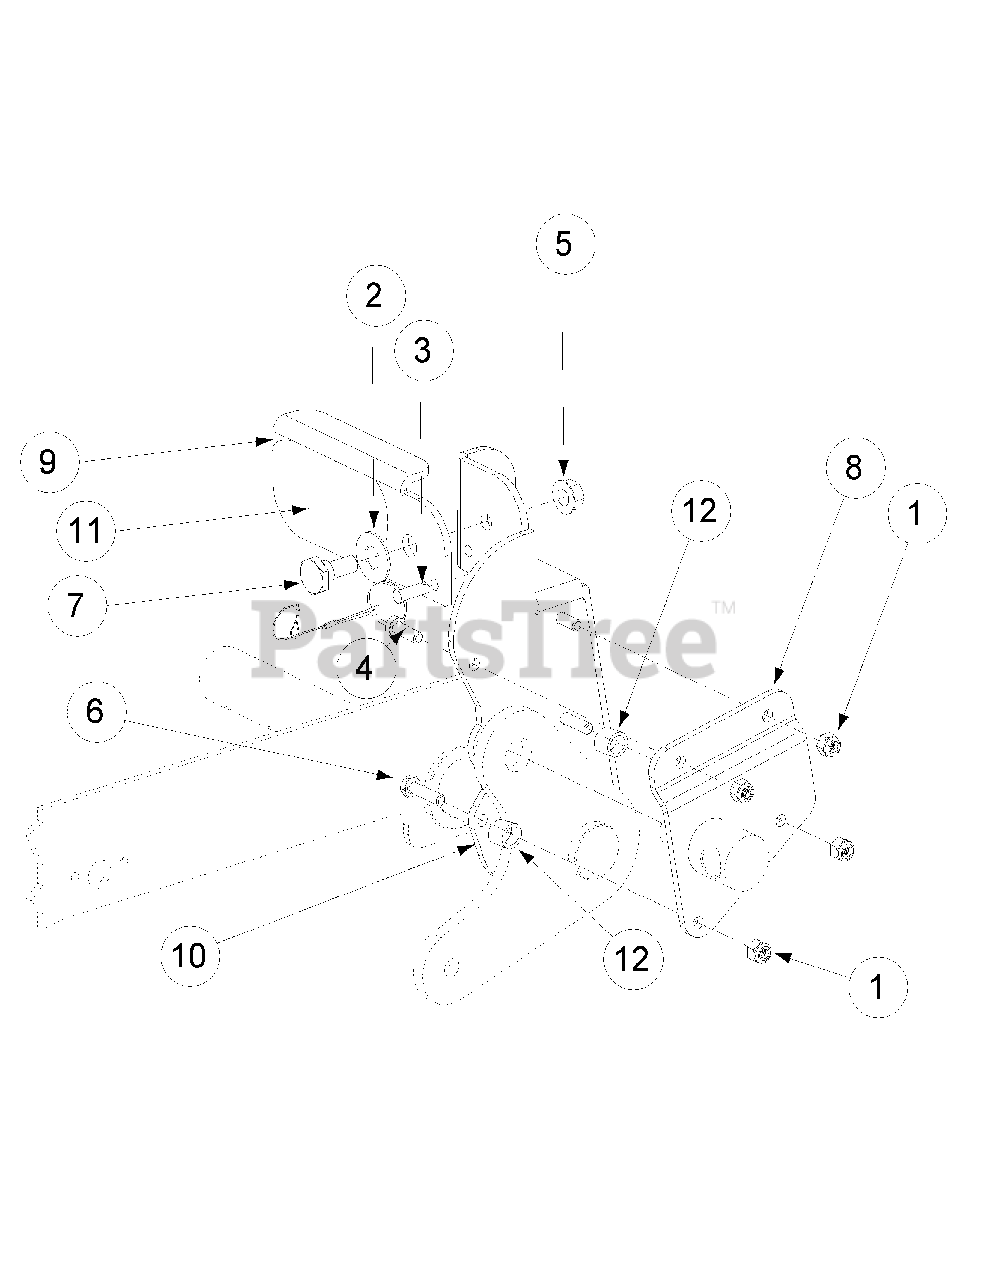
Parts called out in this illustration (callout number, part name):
1	Lock Nut, Nylon Insert, 1/4-20
2	Washer, 1/2 x 1 Shim
3	Detent Pin w/12" Lanyard
4	Hex Cap Screw, 1/4-20, .75
5	Hex Nut, Flange Lock 3/8-16
6	Hex Cap Screw, 1/4-20, 1.00
7	Shoulder Screw, .50 x .27 Lg., 3/8-16
8	Foot Lift Backup Pedal
9	Deck Foot Pedal Lift
10	Deck Foot Pedal Lift
11	Deck Foot Lift Pad
12	Turnbuckle Sleeve
